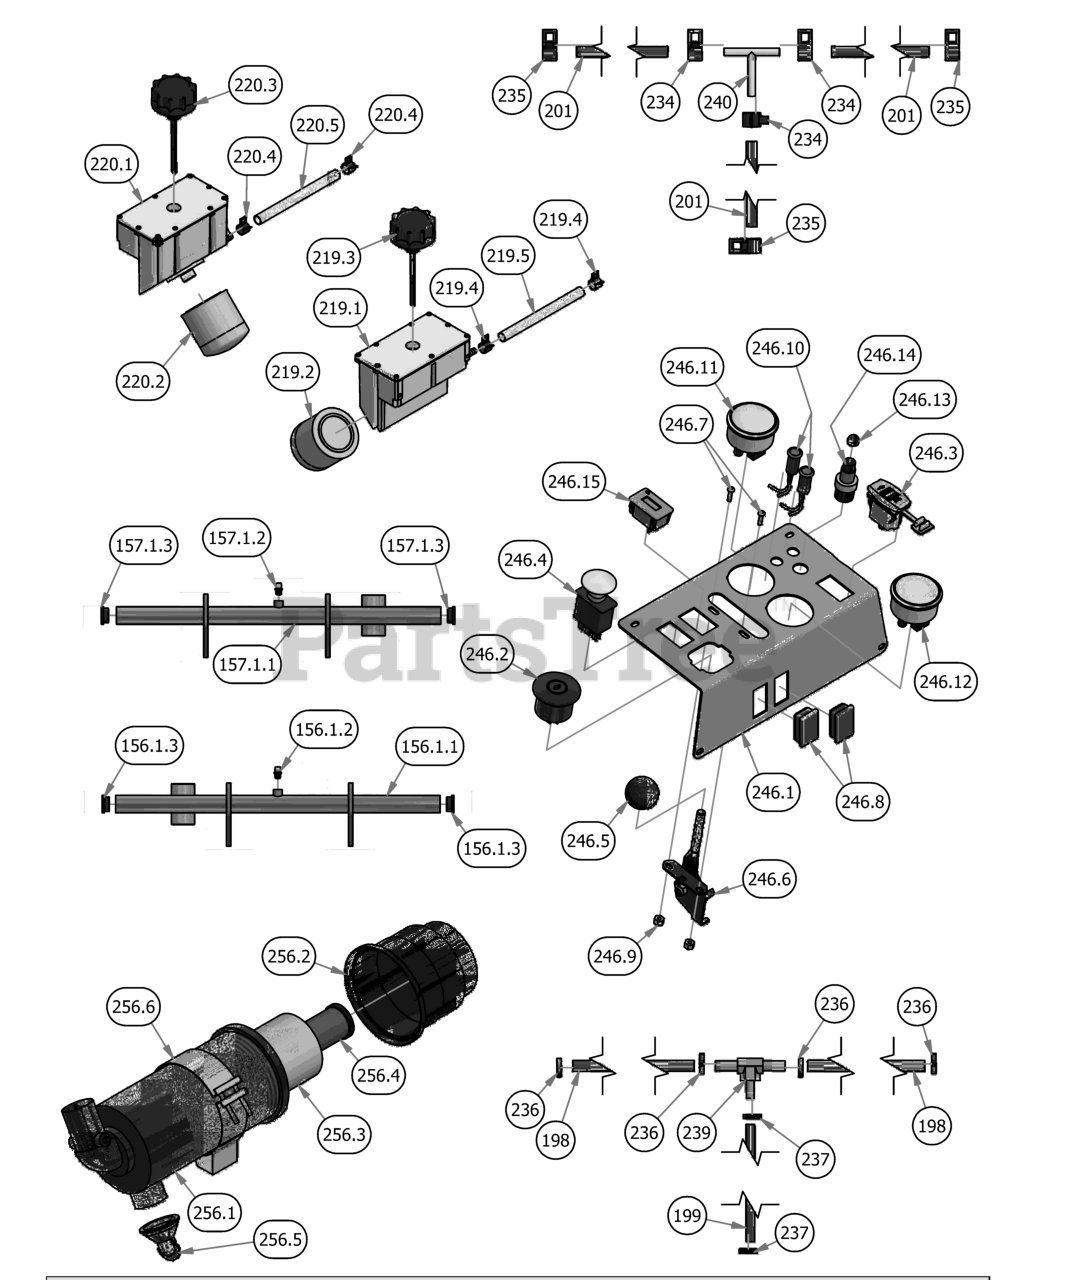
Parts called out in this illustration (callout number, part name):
156.1	2019 Drive Arm Actuator right
156.1.1	2019 Drive Arm Actuator right - Weldment
156.1.2	1/4" Press in Grease Fitting
156.1.3	2019 Drive Arm Bushing
157.1	2019 Drive Arm Actuator left
157.1.1	2019 Drive Arm Actuator left - Weldment
157.1.2	1/4" Press in Grease Fitting
157.1.3	2019 Drive Arm Bushing
198	1/4 Fuel Line Hose - Priced Per Foot
199	3/16 Fuel Line x 36"
201	5/16 Fuel Line Hose - Priced Per Foot
219	LH Rogue Hydro Tank Assy
219.1	2019 Left Outlaw Gen2 Hydro Tank Suspension Only
219.2	Hydraulic Filter
219.3	Hydraulic Tank Cap W/Dipstick
219.4	1/2 Hose Clamp
219.5	1/2 Clear Braded Hose Priced/Foot
220	RH Rogue Hydro Tank Assy
220.1	2019 Right Outlaw Gen2 Hydro Tank Suspension Only
220.2	Hydraulic Filter
220.3	Hydraulic Tank Cap W/Dipstick
220.4	1/2 Hose Clamp
220.5	1/2 Clear Braded Hose Priced/Foot
234	5/16 Hose Clamp
235	5/8 Hose Clamp
236	1/4 Fuel Hose Clamp
237	3/16 Vinyl Clamp
239	Brass fuel line T
240	5/16 x 5/16 x 1/4 Fuel Line T
246	Renegade Control Panel Assembly
246.1	2019 Diesel Control Panel
246.2	Ignition Switch
246.4	PTO Switch
246.5	Throttle Knob
246.6	Universal Throttle
246.7	10-24 X 5/8 BS Button Head Bolt
246.8	Light Plug
246.9	10-24 Nylon Insert Locknut
246.11	2" Oil Pressure Gauge
246.12	2" Water Temperature Gauge
246.13	Start Switch Boot - Diesel
246.14	Momentary Start Switch
246.15	Hour Meter
256	Enginaire Canister VLR-Complet
256.1	Canister for All Diesel Models
256.2	Enginaire Air canister cap
256.3	Diesel Air Filter- Outer
256.4	Diesel Air Filter- Inner
256.5	Debris Plug-Enginaire Filter
256.6	Mounting Bracket For Diesel Air Filter
